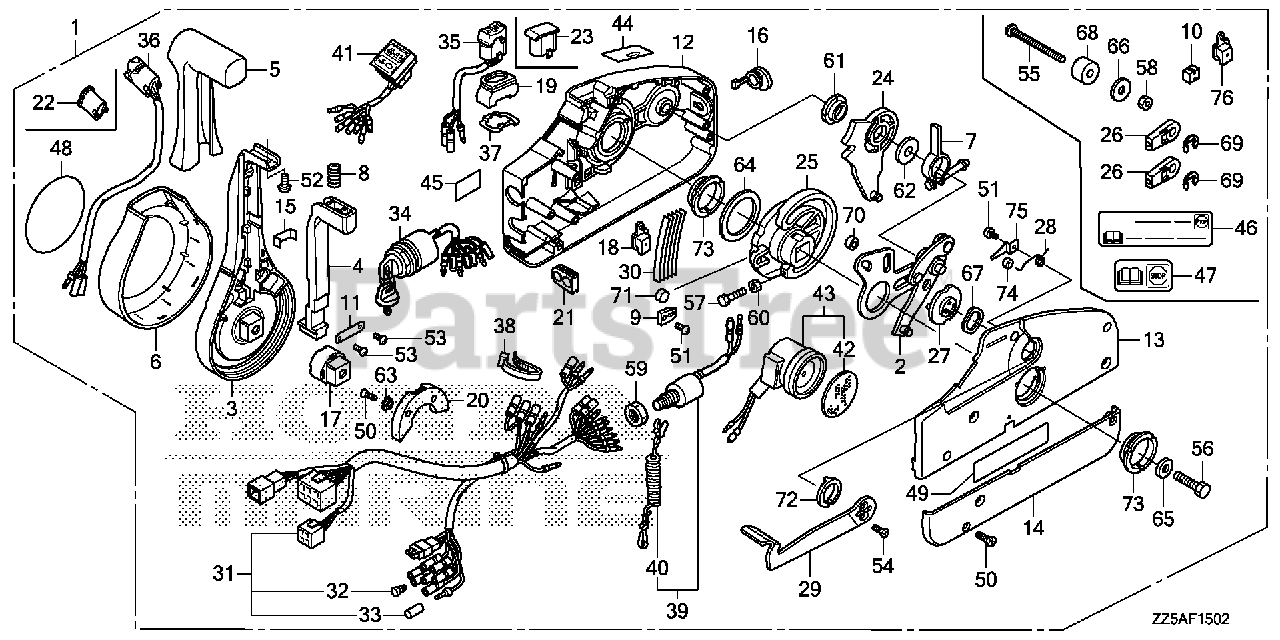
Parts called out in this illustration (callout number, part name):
1	BOX ASSY., REMOTE CONTROL (NHK MEC)
1	BOX ASSY., REMOTE CONTROL (TROLLING CONTROL)(NHK MEC)
2	PLATE ASSY.
3	LEVER, HAND
4	ARM, NEUTRAL LOCK
5	GRIP
6	COVER, LEVER
7	ARM ASSY., BRAKE
8	SPRING (2)
9	CLIP, DETENT
10	SPACER (1) (LOOSE PARTS)
11	BRACKET
12	HOUSING, FR.
13	HOUSING, RR.
14	PANEL, BACK
15	BRACKET, WIRE CLAMP
16	CAP, RUBBER
17	ADJUSTER
18	COVER, POWER TRIM-TILT WIRE
19	SEAL, RUBBER
20	HOLDER, NEUTRAL LOCK
21	GROMMET, WIRE (14)
23	CAP, TROLLING CONTROL SWITCH BLANK
24	GEAR ASSY., SHIFT
25	GEAR, DRIVE
26	TERMINAL, CABLE (LOOSE PARTS)
27	DRUM ASSY., FREE THROTTLE
28	SPRING (1)
29	LEVER, FREE THROTTLE
30	SPRING, DETENT
31	CABLE ASSY., REMOTE CONTROL (B)
31	CABLE ASSY., REMOTE CONTROL (B)(TROLLING CONTROL)
32	PLUG, CONNECTOR (INNER) (TROLLING CONTROL)
33	PLUG, CONNECTOR (OUTER)
34	SWITCH ASSY., COMBINATION
35	SWITCH ASSY., TROLLING CONTROL
36	SWITCH ASSY., POWER TRIM-TILT
37	PLATE, SWITCH
38	BAND, WIRE
39	SWITCH ASSY., EMERGENCY STOP
40	WIRE, EMERGENCY
41	LAMP ASSY., INDICATION
42	PLATE, TURN SIGNAL BUZZER
43	BUZZER, WARNING
44	MARK, FAST IDLE
45	MARK, EMERGENCY STOP (US)
46	MARK, EMERGENCY STOP (US) (LOOSE PARTS)
48	MARK, EMBLEM
49	LABEL, SIGP
50	SCREW (5X18)
51	SCREW (4X6)
52	SCREW (5X10)
53	SCREW (4X10)
54	SCREW (5X12)
55	SCREW (6X90) (LOOSE PARTS)
56	BOLT (8X50)
57	BOLT (5X25)
58	NUT (6MM) (LOOSE PARTS)
59	NUT, HEX. (16MM)
60	NUT (5MM)
61	BEARING (1)
62	WASHER (3)
63	WASHER (4)
64	WASHER (5)
65	WASHER (8MM)
66	WASHER (7) (LOOSE PARTS)
67	WASHER, WAVE
68	SPACER (2) (LOOSE PARTS)
69	E-RING (6MM) (LOOSE PARTS)
70	ROLLER, DRIVE GEAR CAM
71	ROLLER
72	BEARING (2)
73	BEARING (3)
74	ROLLER, FREE THROTTLE
75	CLIP, ROLLER
76	COVER, POWER TRIM-TILT WIRE (LOOSE PARTS)
